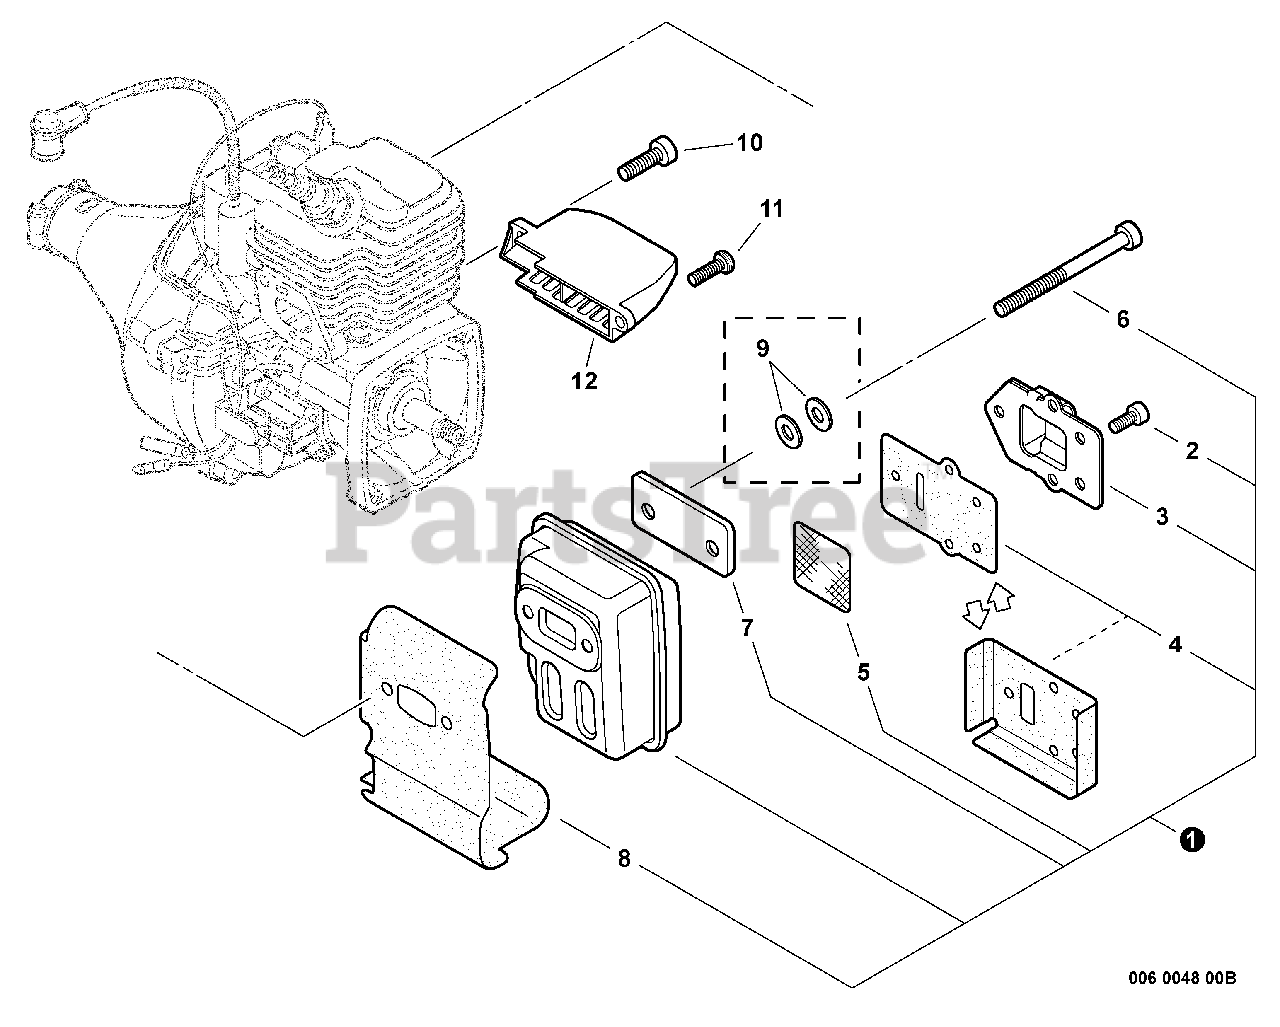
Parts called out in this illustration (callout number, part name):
1	MUFFLER ASSY
2	SCREW - 4X8
3	GUIDE, EXHAUST
4	GASKET, EXHAUST
5	SCREEN, SPARK ARRESTOR
6	SCREW - 5X55
8	SHIELD, EXHAUST
9	WASHER - CONICAL
10	SCREW - 5X16
11	SCREW - 5X16
12	DUCT, AIR
